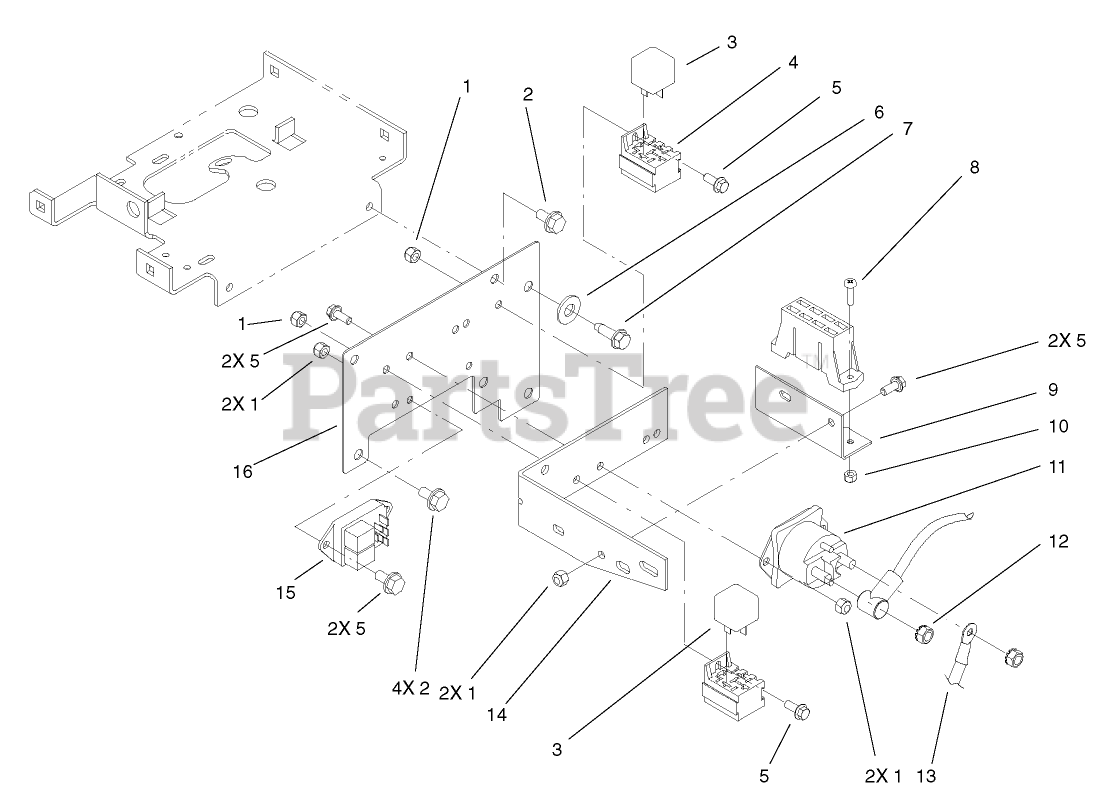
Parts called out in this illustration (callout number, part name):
1	NUT-LOCK, NI
2	SCREW-HWHTF
3	RELAY
4	HARNESS-WIRE
5	SCREW-HHF
6	WASHER-FLAT
7	SCREW-TAPTITE
8	SCREW-PAN
9	FUSE HOLDER
10	NUT-LOCK, NI
11	SOLENOID
12	NUT-KEPS
13	CABLE-BATTERY, POSITIVE
14	BRACKET-BELT
15	MODULE-CLUTCH
16	PLATE-HOODSTAND, FRONT
